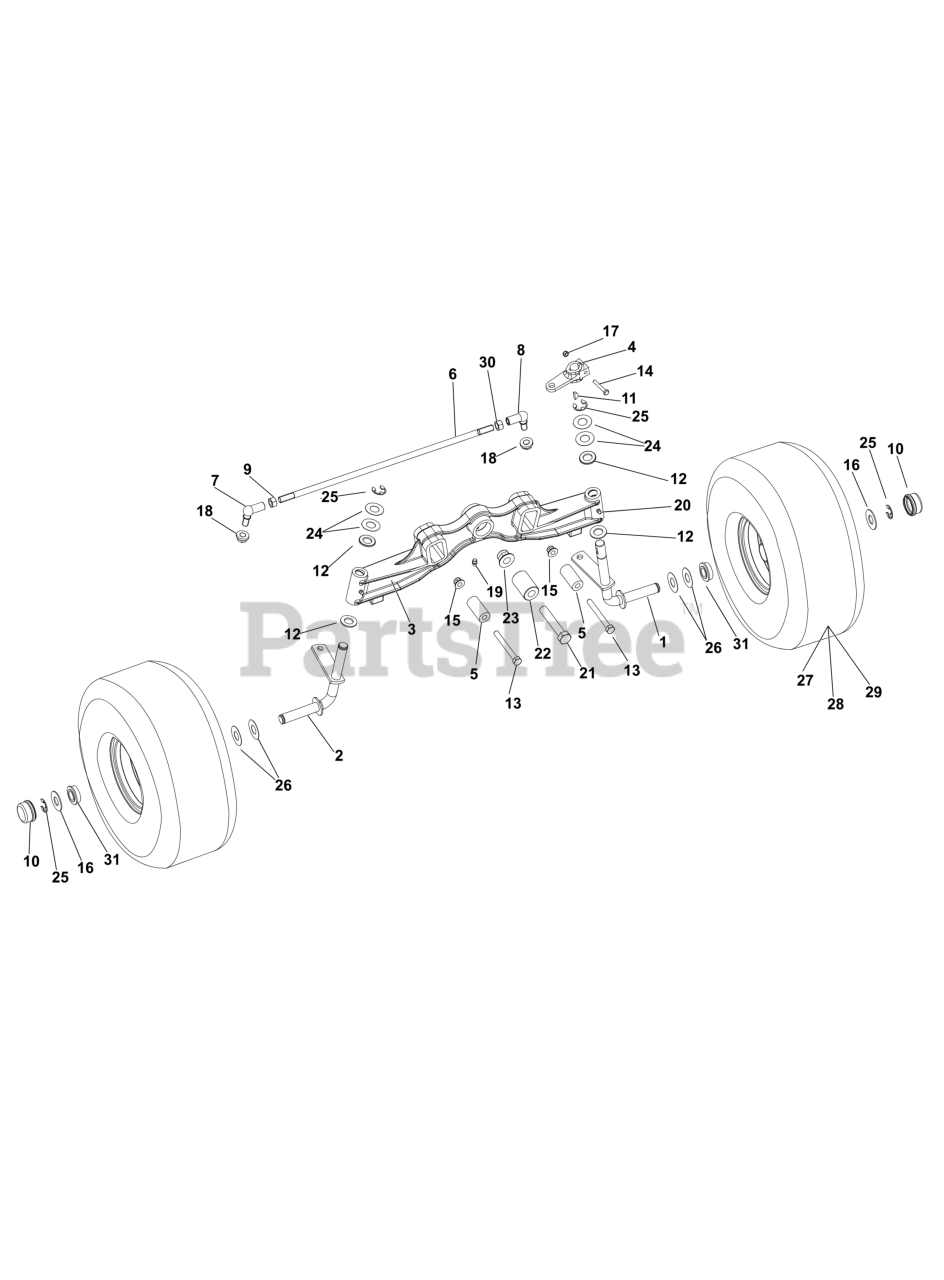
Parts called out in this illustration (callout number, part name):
6	ROD, Connecting
7	JOINT, BALL
8	JOINT, BALL
9	NUT M12 L
19	ZERK, Grease Fitting
20	ZERK, Grease Fitting
25	RING, Locking
27	WHEEL, Front
